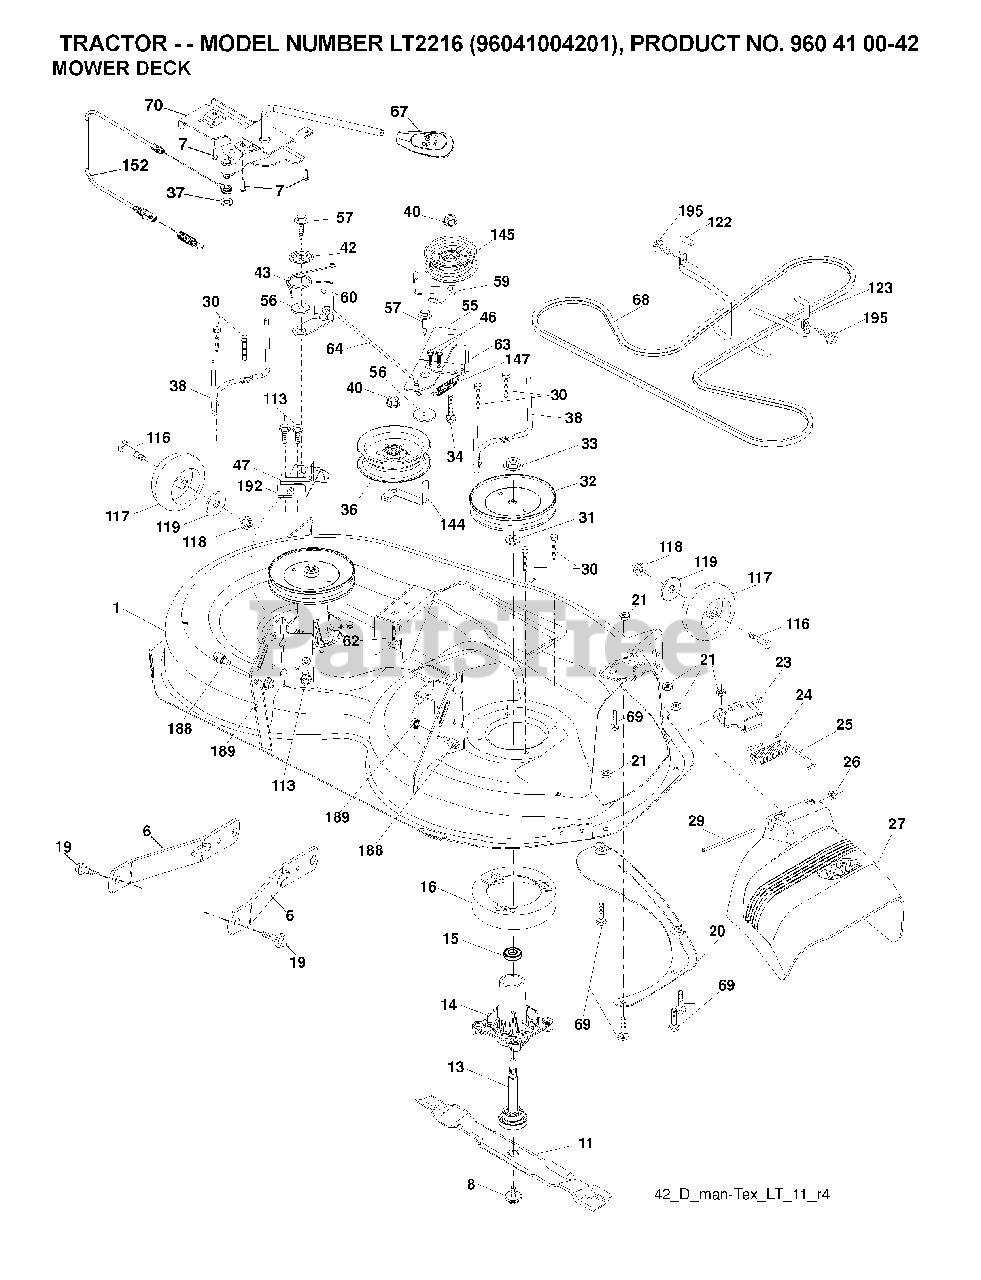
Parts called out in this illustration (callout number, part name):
1	DECK.WELDMENT.42"
6	ARM.SUSPENSION.MOWER.R
7	SCREW.#10 X 0.750.BOS THREAD
8	BOLT.WASHER.ASM.7/16-2
11	42" HI-LIFT BLADE
13	SHAFT.ASM.MDRL.N/GREASE.38
14	HOUSING MANDREL
16	STRIPPER, MWR ROUND
19	BOLT.SHOULDER
20	BAFFLE.VORTEX
21	LOCKNUT
23	BRKT.DEFLECTOR.38"2005+
24	CAP-SLEEVE LT
25	SPRING.TORSION.DEFLECT
26	NUT PUSH M
27	SHIELD.DEFLECTOR.MOWER.42"BLAC
29	ROD.HINGE
30	SCREW, WASHER HEAD
31	WASHER.SPACER.MANDREL
32	PULLEY.MANDREL.5.438.PD
33	NUT.FLANGE.LOCK.TOP
34	BOLT.3/8-16X1.50
36	PULLEY.IDLER.2006
38	KEEPER.BELT.LH.MANDREL
40	NUT LOCK FLG 3/8-16 UNC
42	SPRING.TORSION.BRAKE
43	SRPING.TORSION.RETAINE
46	SCREW.1/4-20X5/8
47	BRKT.CLUTCH.CABLE
55	IDLER.ARM
56	SPACER.RETAINER
57	SCREW 3/8-16X1
59	GUARD, BELT
60	ARM BRAKE MOWER
62	BOLT
63	ARM BRAKE MOWER RH
64	LINK BRAKE
67	HANDLE.CLUTCH.CABLE.LT
68	BELT.DRIVE.MOWER.TEX.42"
69	BOLT
70	CLUTCH.ASM.MANUAL.LT.TEX
113	BOLT.5/16HEX.WHS.HD
115	BOLT
117	WHEEL.GAGE.HALF.SPOKED
118	LOCKNUT
119	WASHER
122	KEEPER BELT ENGINE LH
123	KEEPER BELT RH
144	KEEPER.BELT.MOWER
145	PULLEY.IDLER.48"PRIMARY
147	RETURN SPRING
149	SPRING.RETAINER.YELLOW.ZINC
152	CLUTCH CABLE
188	STUD.FASTNER.W/ANTI-ROTATE
189	NUT LOCK HEX FLANGE 5/16-18
192	BRKT.BRAKE.STAND.LH.
195	SCREW, 3/8-16X3/4
